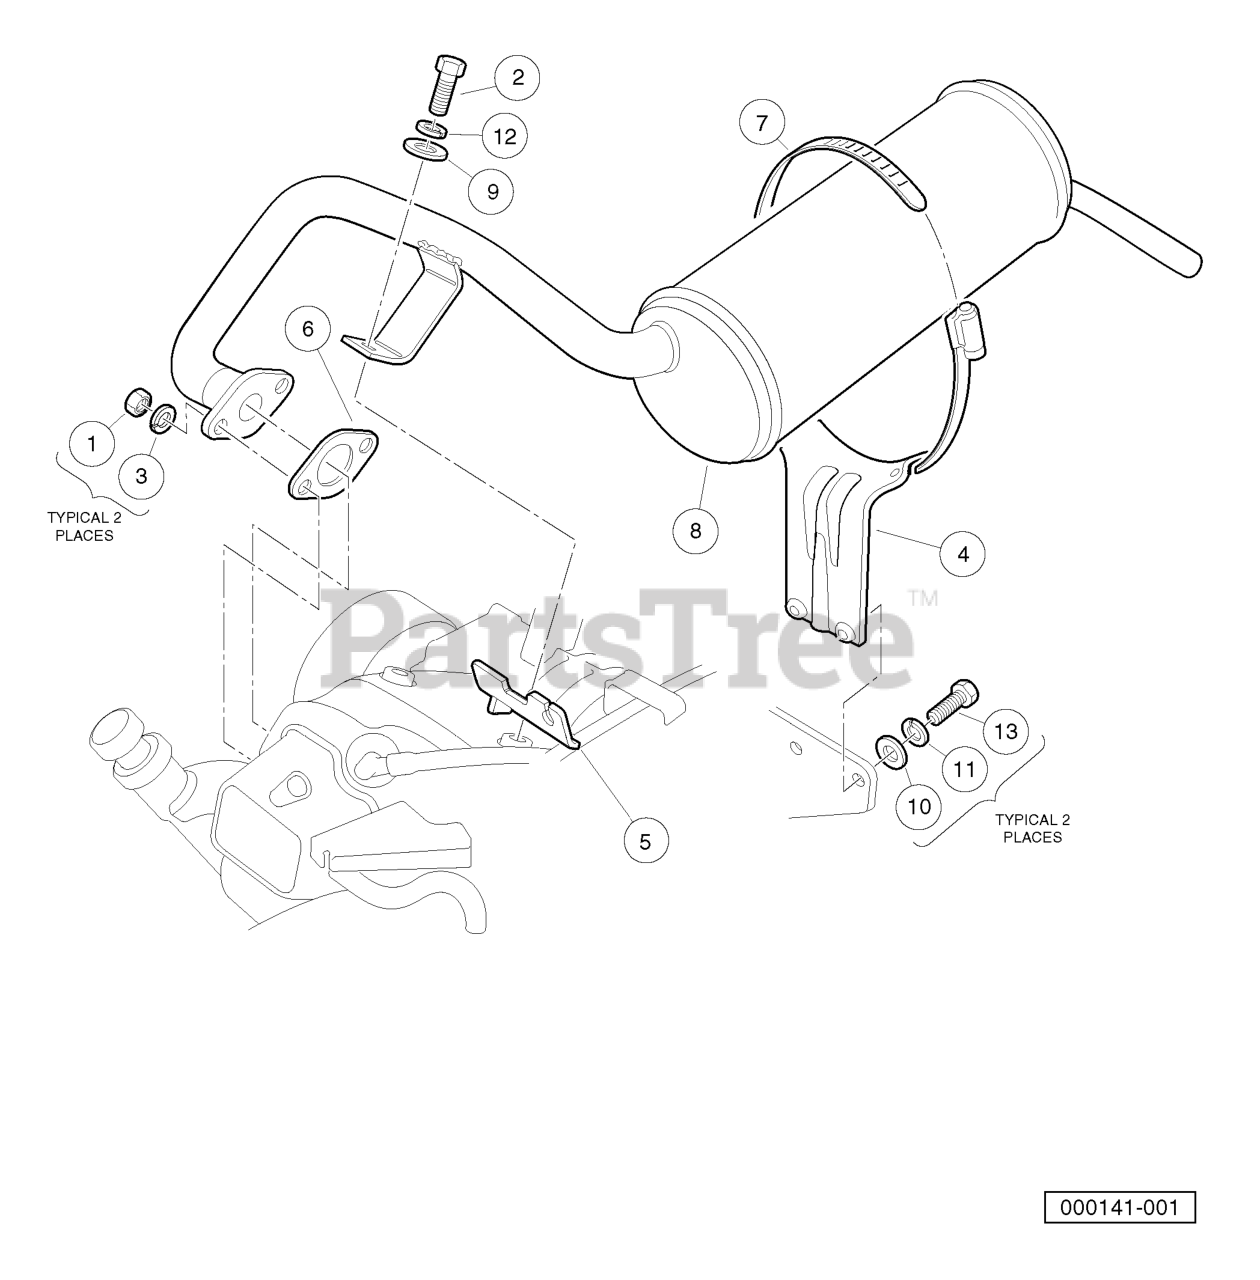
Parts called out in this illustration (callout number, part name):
1	NUT, M8-1.25 HEX
4	BRACKET, MUFFLER MOUNTING
7	CLAMP, 5" MUFFLER HOSE
8	EXHAUST SYSTEM, FE400
9	WASHER, 5/16 TYPE A FLAT
10	WASHER 1/4 FLAT
11	LOCKWASHER, 1/4 HELICAL SPLIT
12	LOCKWASHER, 5/16 SPLIT
13	SCREW, 1/4-20 X .75 HEX
